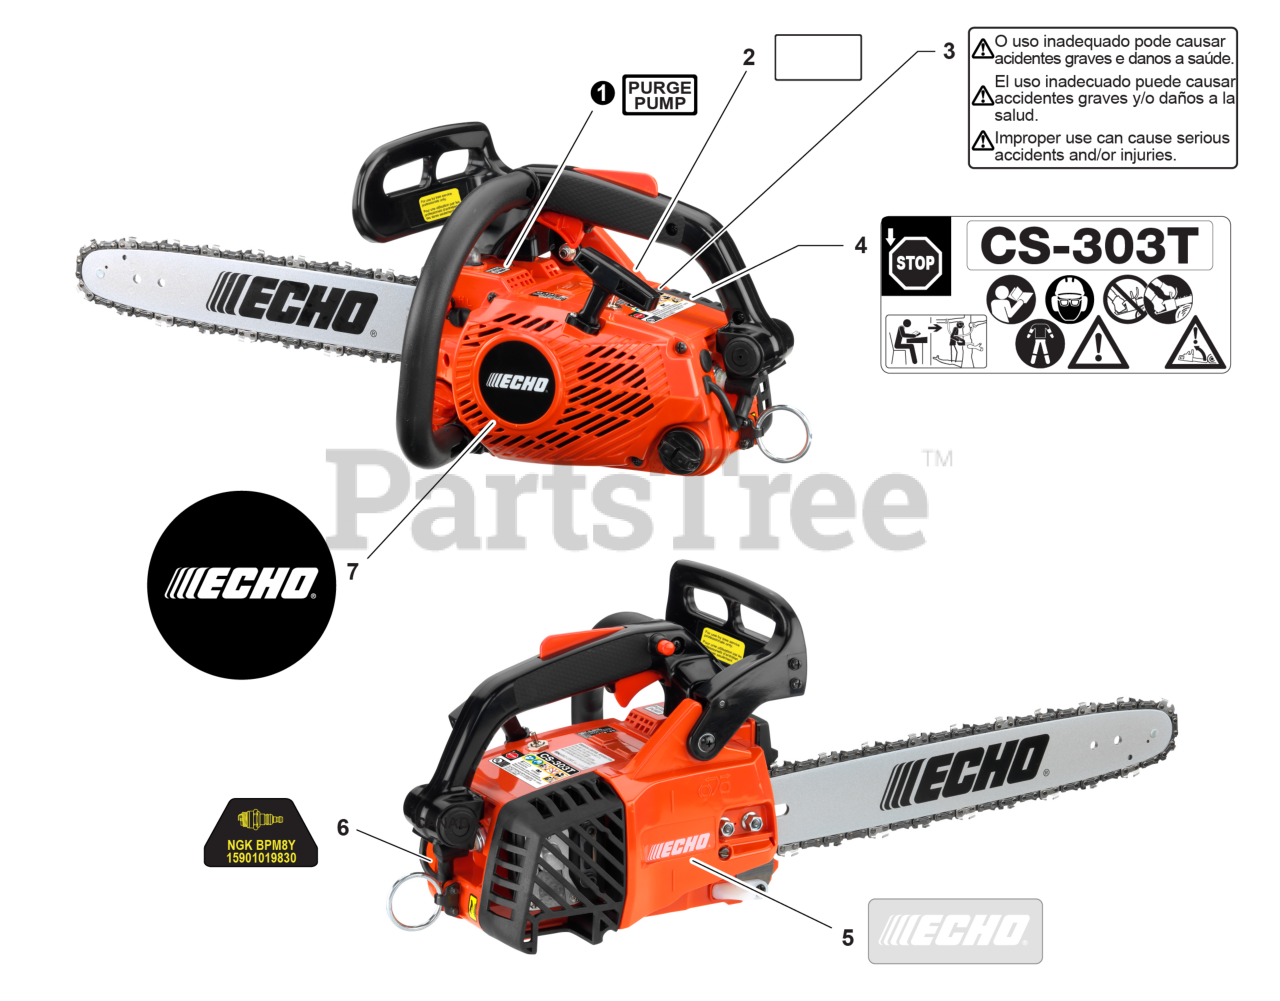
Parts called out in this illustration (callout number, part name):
1	LABEL - PURGE PUMP
2	LABEL - JAPAN TECHNOLOGY
3	LABEL - CAUTION
4	LABEL - MODEL CS-303T
5	LABEL - ECHO
6	LABEL - SPARK PLUG - BPM8Y
7	LABEL - RECOIL STARTER
